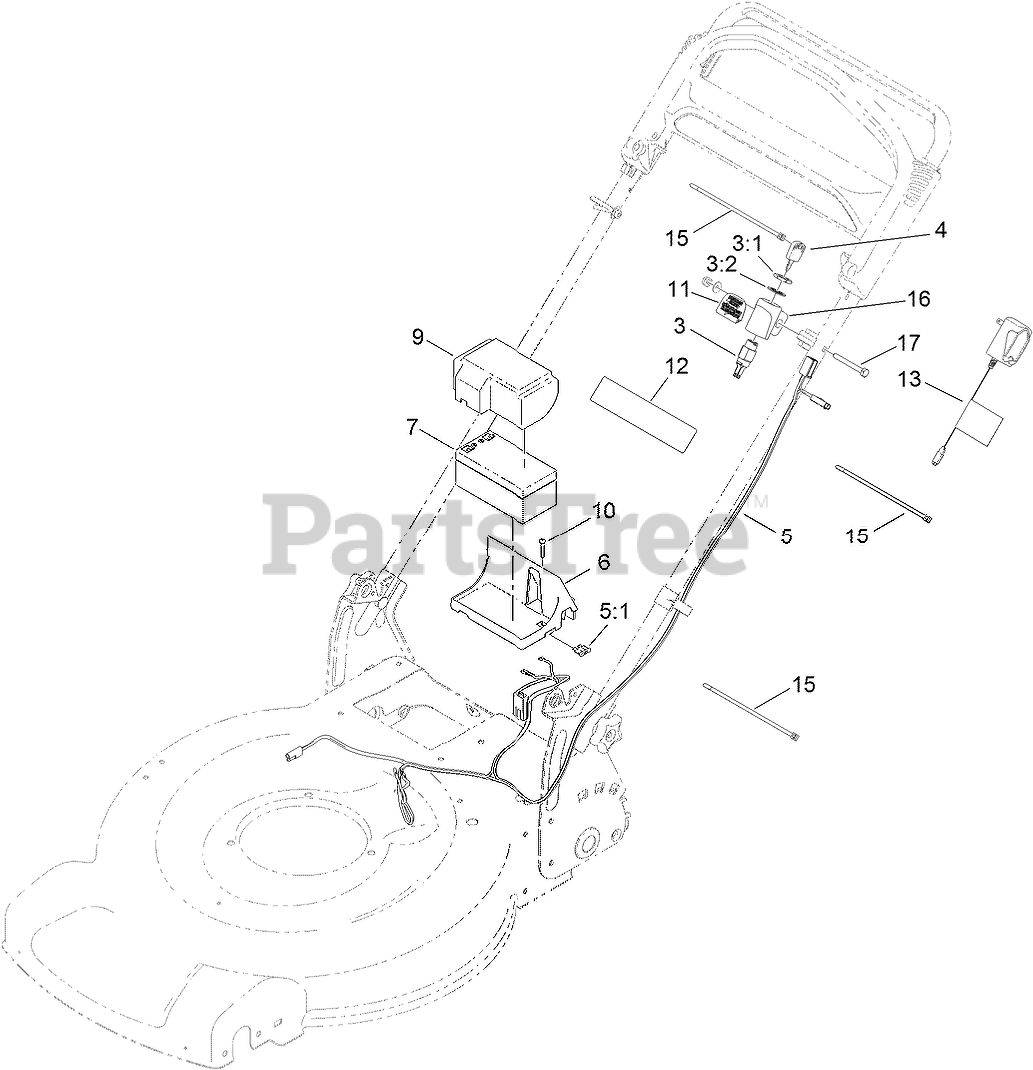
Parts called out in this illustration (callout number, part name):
3	STARTER SWITCH ASM
3:1	WASHER-TOOTH, INTERNAL
3:2	NUT-HH
5	HARNESS-WIRE, ES
5:1	FUSE-40 AMP
6	TRAY-BATTERY
7	BATTERY-WET
9	COVER-BATTERY
10	SCREW-PPH, PLASTITE
11	DECAL-ELECTRIC START
12	DECAL-WARNING
13	CHARGER-BATTERY
15	TIE-CABLE
16	MOUNT-SWITCH
17	SCREW-HH
